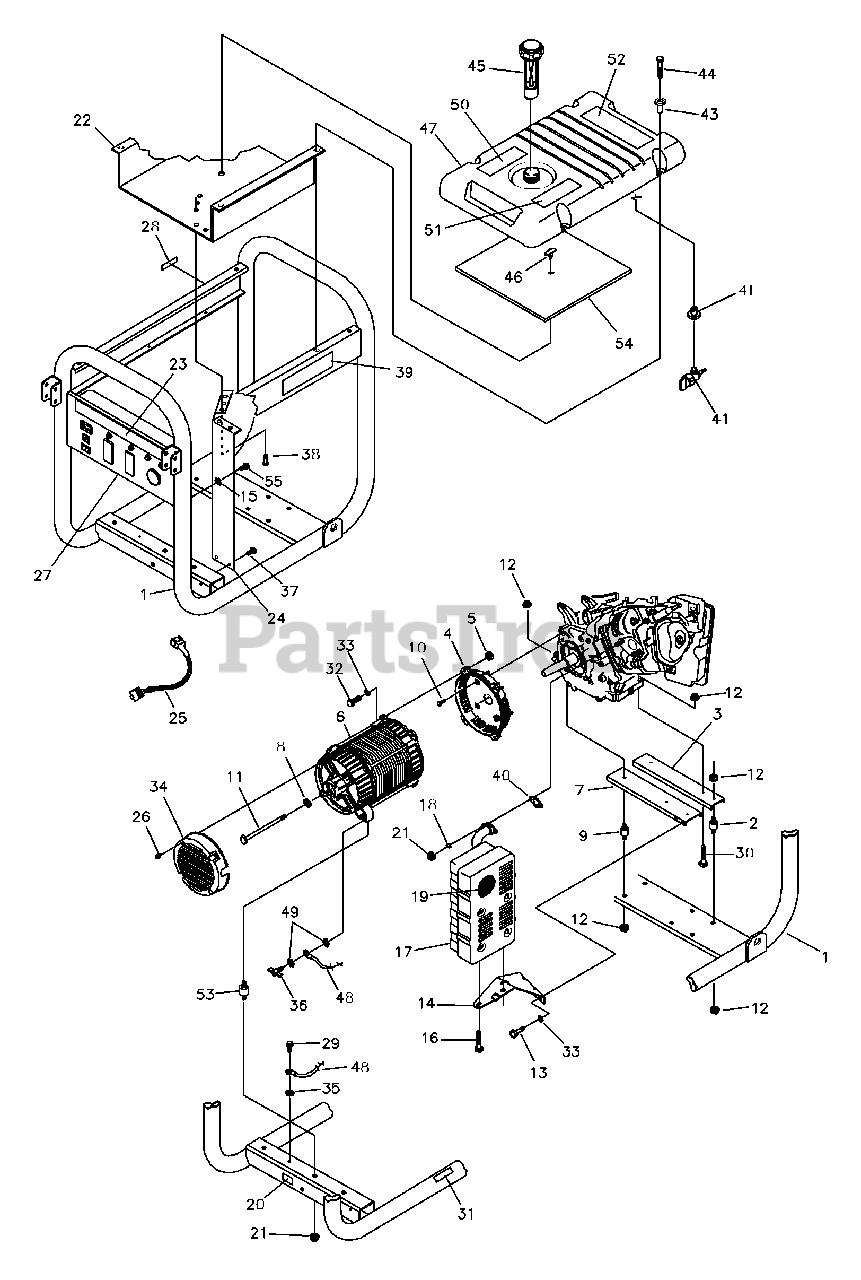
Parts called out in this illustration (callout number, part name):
2	MOUNT,Vibration
3	SUPPORT, Engine
4	HOUSING, Engine Adapter
6	ASSY,Alternator
7	SUPPORT, Eng/Muffler
9	MOUNT,Vibration
14	BRACKET, Muffler
16	SCREW, w/Lock Washer
19	SCREEN, Spark Arrest
20	DECAL, Ground
21	NUT, Flange Serrated
22	SHIELD, Heat
23	DECAL, Panel, Control
24	SHIELD, Heat
25	HARNESS,Wire, Power
27	ASSY, Control Panel
28	DECAL, Fuel Shut-off
31	DECAL, Hot Muffler
33	WASHER, Lock
34	COVER, Bearing Carrier
36	SCREW,Wing
39	DECAL, Unit
40	GASKET, Muffler (with Item 900)
41	KIT,VLV, FUEL, SRV
43	GROMMET,Tank
45	CAP, Fuel Gauge
46	CLIP, Insulation
47	ASSY,Tank, Fuel
48	WIRE, Ground
50	DECAL, Instruction, Fuel Level
51	DECAL, Danger
52	DECAL, Start Instructions
53	MOUNT,Vibration
54	INSULATION
900	ENGINE
